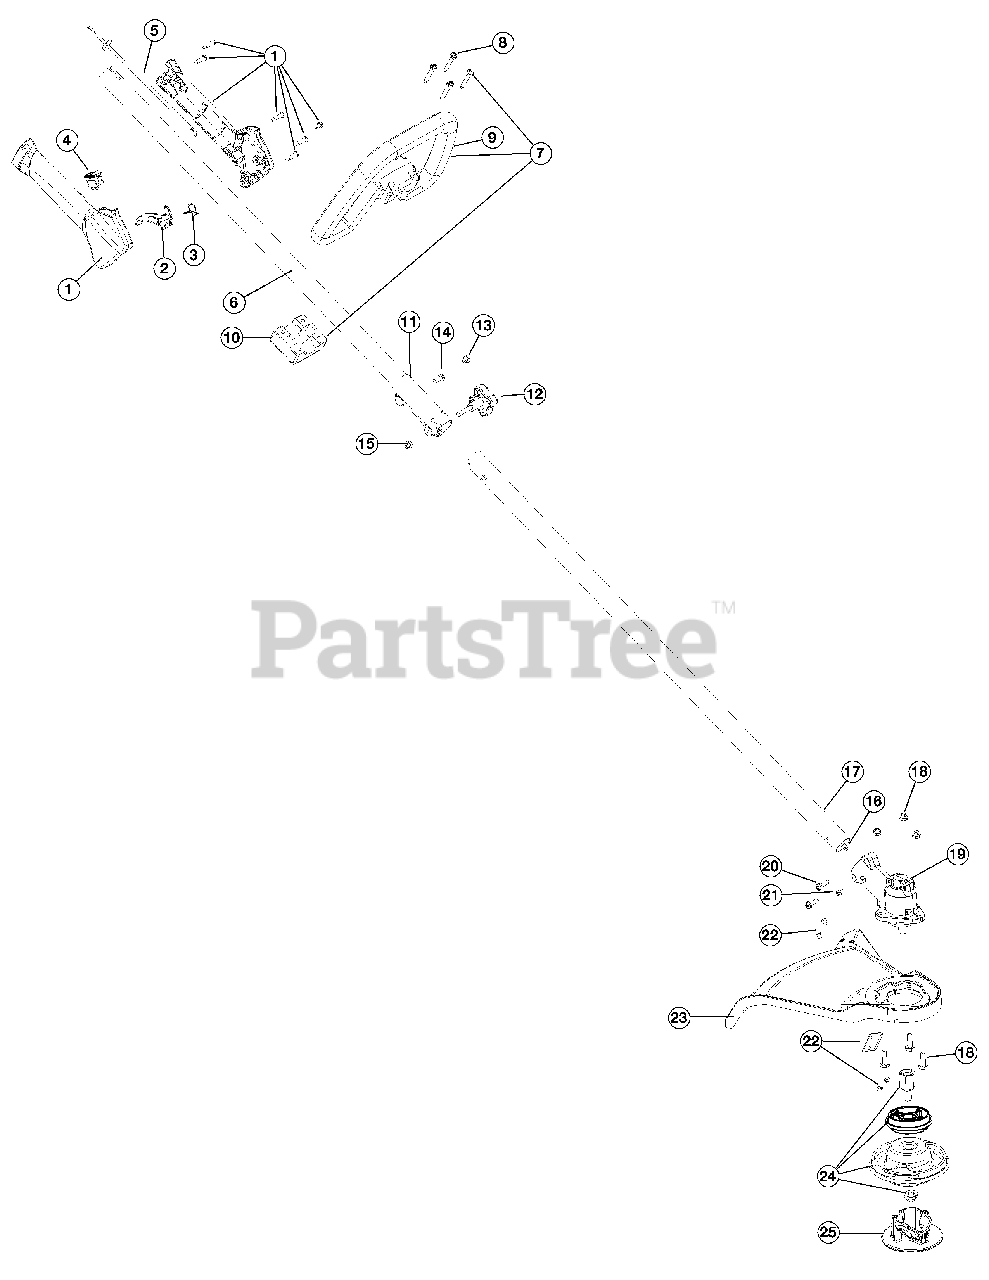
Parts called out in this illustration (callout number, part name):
1	Throttle Housing Assembly (includes 2-4)
2	Throttle Trigger
3	Throttle Trigger Spring
4	Switch Assembly
5	Throttle Cable Assembly
6	Upper Drive Shaft Housing
7	Deluxe D-Handle Assembly (includes 8-10)
9	D-Handle
10	D-Handle Base
11	Split Boom Coupler (includes 12-15)
12	Adjustment Knob (includes 15)
15	Nut
16	Lower Flexible Drive Shaft
17	Lower Drive Shaft Housing
18	Shield Mount Screw Assembly
19	Gearbox Assembly
20	Gearbox Screw
21	Anti-Rotation Screw
22	Blade Assembly
23	Shield Assembly (includes 22)
24	Cutting Head Assembly
25	Cutting Head Cap
